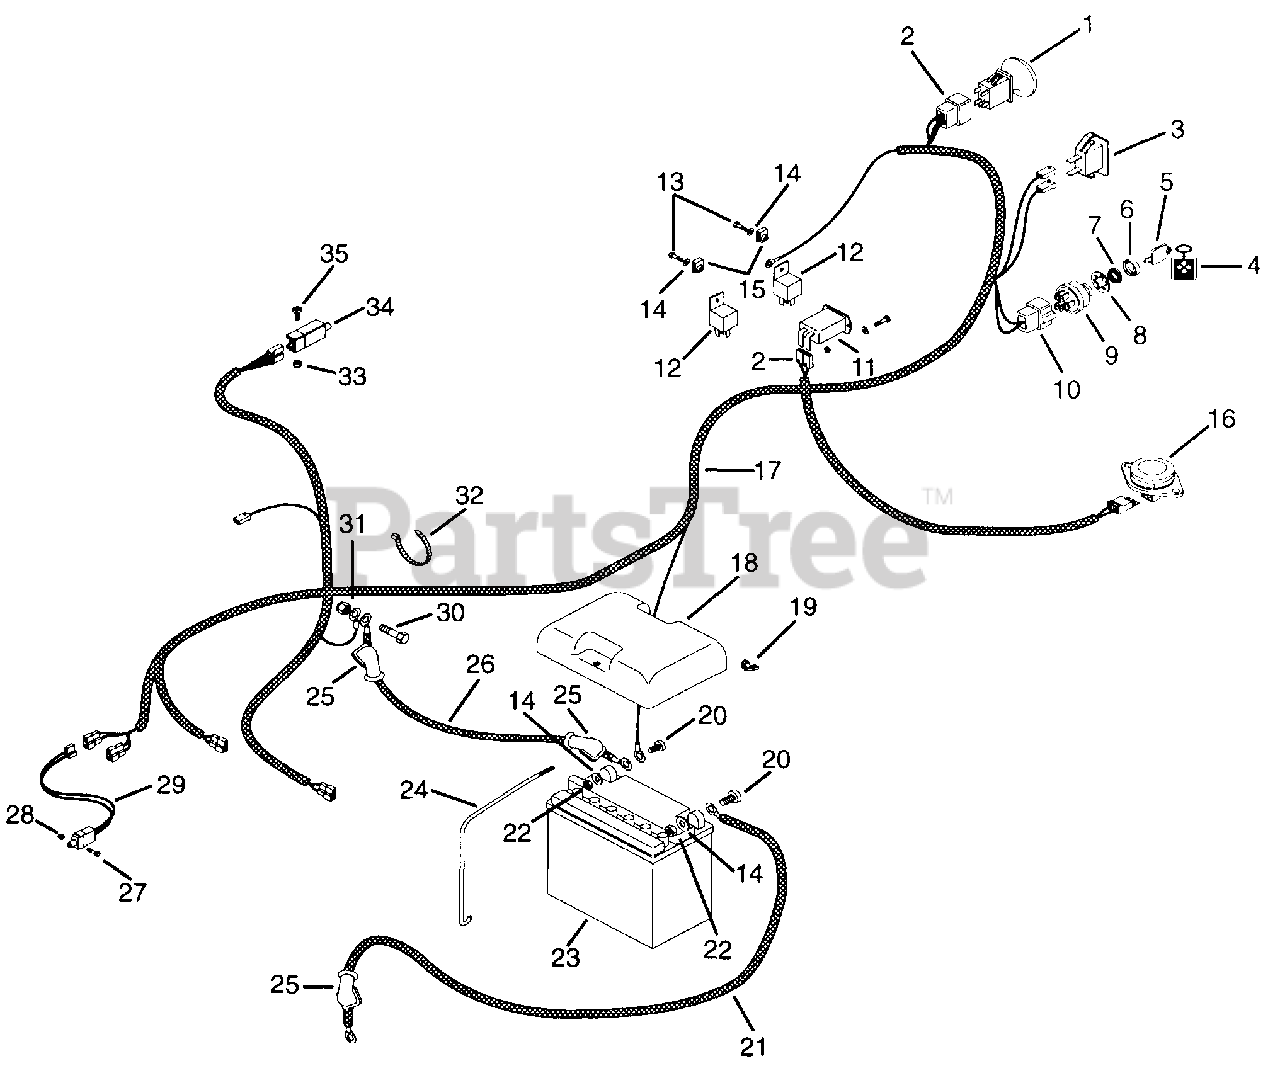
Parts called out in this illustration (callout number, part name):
1	Switch, Clutch with Retainer Ring
2	Terminal
3	Light, Indicator
4	Key Chain
5	Ignition Switch Key
6	Cap-Ignition Switch
7	Nut-Panel .562-24
8	Washer-Lock-Internal .563 x .040
9	Key Switch
10	Connector
11	Hour Meter
12	Relay
13	Screw-Machine .25-20
14	Washer-Flat-Steel .281 x .620 x .065
15	Nut-Speed .25-20
16	Seat Switch
17	Wire Harness
18	Cover, Battery
19	Nut-Wing .250-20
20	Bolt-Hex .25-20 x .75 Grade 5
21	Cable, Starter
22	Nut-Hex .250-20
23	Battery
24	Rod, Battery
25	Boot, Insulator
26	Cable, Negative Battery
27	Screw-Machine 6-32 x .875
28	Nut-Locking-Machine 6-32
29	Switch
30	Bolt-Hex .31-18 x 1.00 Grade 5
31	Nut-Locking-Nylon.312-18
32	Tie, Wrap, Black
33	Nut-Locking 10-24
34	Switch, Interlock
35	Screw-Machine 10-24 x .625
